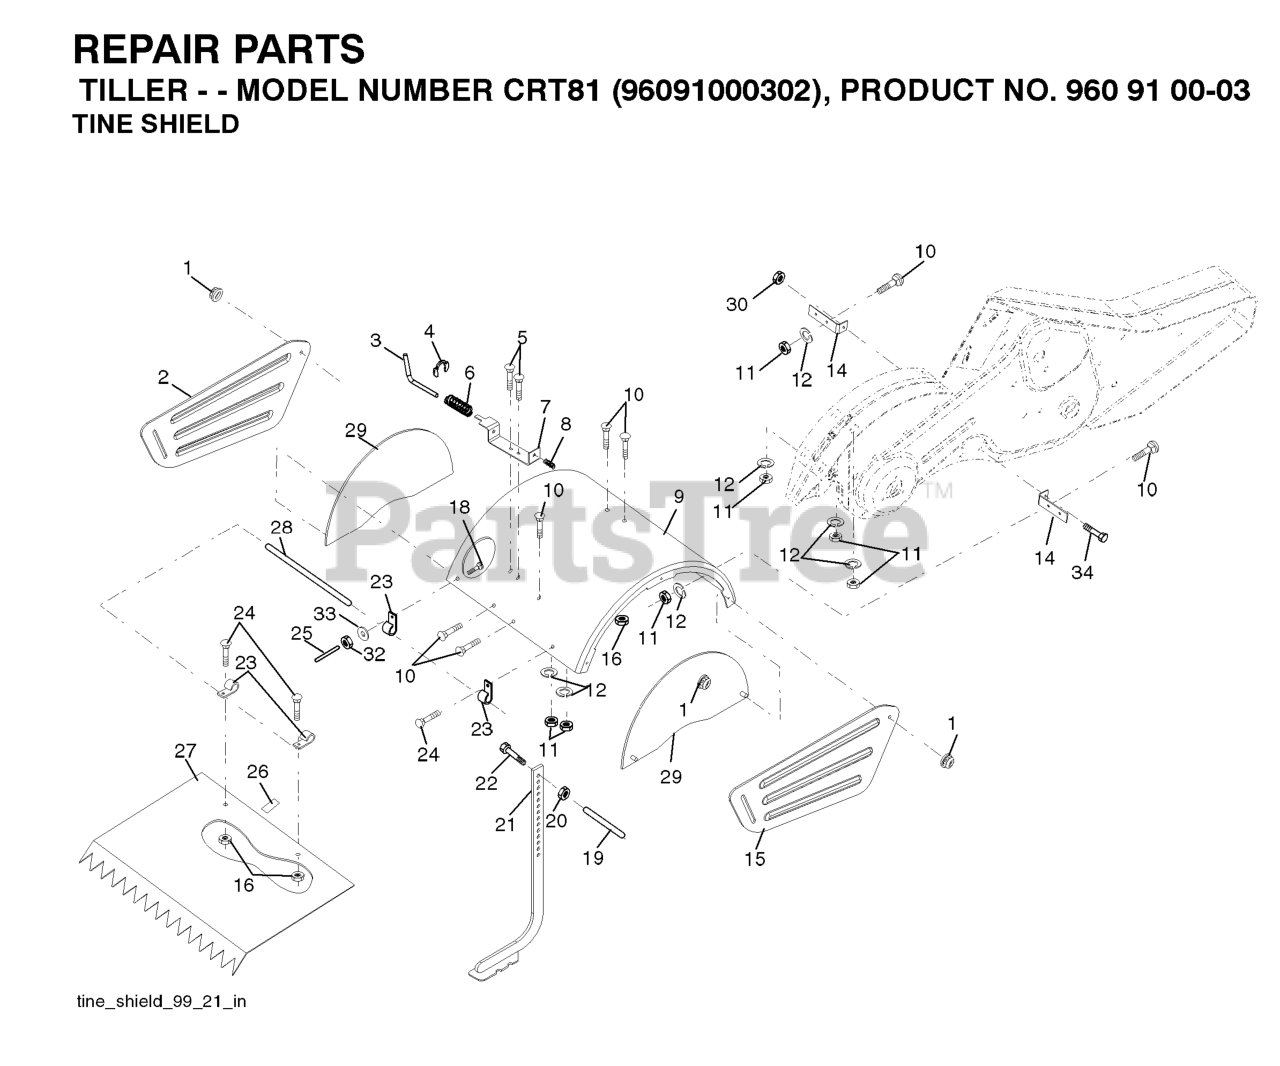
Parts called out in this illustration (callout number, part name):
1	NUT LOCK HEX FLANGE 5/16-18
2	TINE SHIELD
3	STAKE PIN TI
4	RING, KLIP
5	BOLT, RDHD SQNK 5/16-18 X 3/4
7	BRACKET.LATCH.STAKE.3.20.BLACK
8	SPRING CRT
9	SHIELD TINE
12	WASHER.LOCK.HVY.HLCL.SPR.5/16
14	BRACKET.TINE.SHIELD.TILLER
15	SHIELD
16	NUT T
20	NUT.HEX.3/8-16UNC
21	STAKE.ASM.DEPTH
22	BOLT.375-16
25	VINYL CAP TI
26	PAD IDLER TI
27	SHIELD.LEVELING.21".ORANGE
28	PIN, HINGE
29	SHIELD, SIDE
30	LOCKNUT-FLANGE 5/16-18
32	NUT
33	LOCKWASHER
34	Bolt Hex Flanged 5/16-18 Unc x 2
